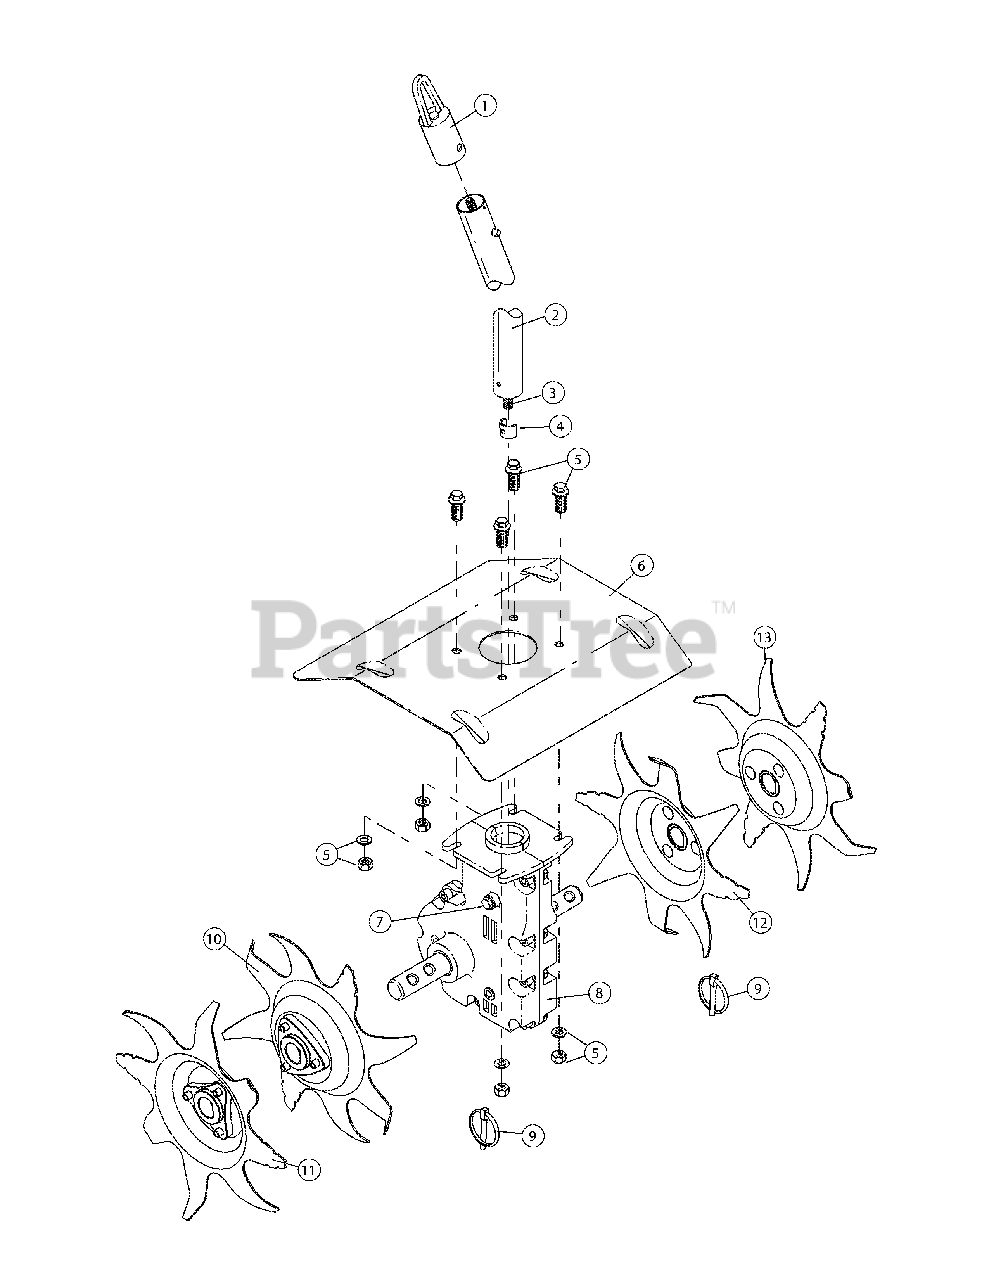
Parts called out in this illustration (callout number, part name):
1	Accessory Hanger
2	Drive Shaft Housing Assembly
3	Flexible Drive Shaft
4	Retainer Sleeve
5	Guard Mounting Hardware Set
7	Screw, Hex Wash Tapp 1/4 x .50 Lg
8	Gear Box Assembly
10	Right Inner Tine
11	Right Outer Tine
12	Left Inner Tine
13	Left Outer Tine
